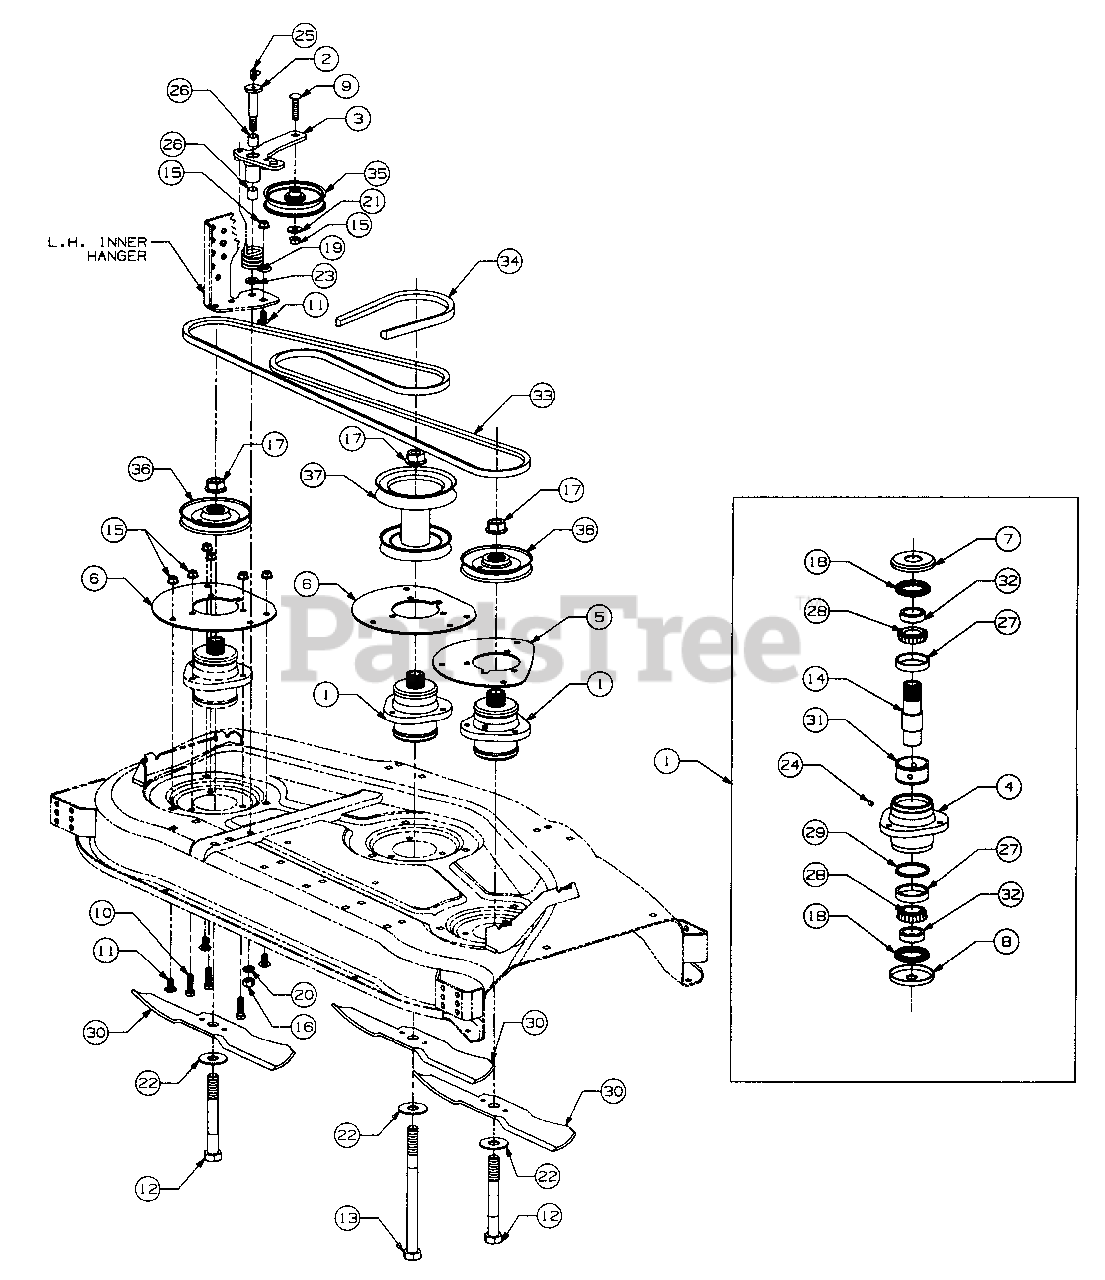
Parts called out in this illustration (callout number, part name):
1	Spindle Assy, Complete
2	Bolt, Shoulder
7	Cup, Top Spindle
9	Bolt, Carriage, 3/8-16 X 1.75 Lg
10	Screw, Hex Cap, 3/8-16 X 1.25 Lg GR5
11	Bolt Sht Nk Carriage, 3/8-16 X .75 Lg GR5
12	Bolt, Hex Hd Blade, 3/4-16 X 6.0 Lg
13	Bolt, Hex Hd Blade, 3/4-16 X 9.50 Lg
14	Shaft, Blade Spindle
15	Nut, Hex Flanged Lock, 3/8-16
16	Nut, Hex 7/16-14 GR5
17	Nut, Hex Flange, 3/4-16
18	Seal, Oil
19	Spring, Torsion
20	Washer, Lock, 7/16
21	Washer, Spec, .378 X 1.0 X .125 Thk
22	Washer, Flat, .781 X 2.0 X .105 Thk
23	Washer, Flat, .469 X .875 X .105 Thk
24	Fitting, Lube
25	Fitting, Lube, 90 Degree 1/4-28 Tapper Thd
26	Bearing, Sleeve
27	Cup, Bearing
28	Cone, Bearing
29	Spacer, Bearing
30	Blade, Mower, 16.5 Lg
31	Spacer, Bearing Cup
32	Ring, Seal
33	Belt, Spindle, A-Sect X 107.3 Lg
34	Belt, PTO, B-Sect X 62.04 Lg
35	Pulley, Flat Idler
36	V-Pulley, 4.65 OD
37	Pulley, Deck, 5.07 OD & 5.75 OD
